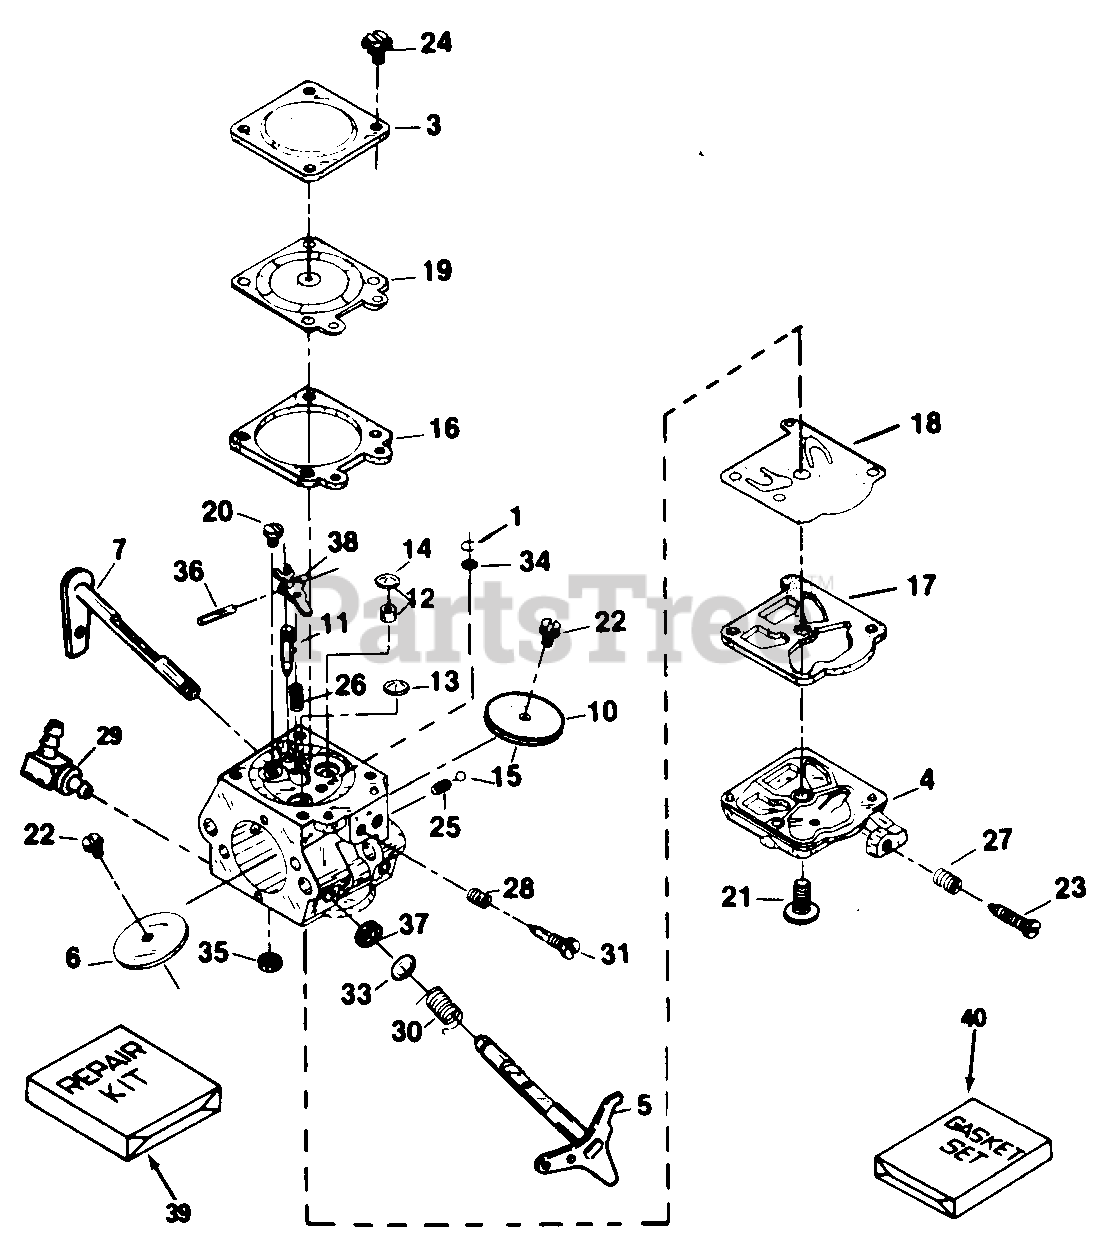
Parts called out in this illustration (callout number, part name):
1	Ring, Screen Retaining
3	Cover, Metering Diaphragm
4	Cover, Pump
5	Shaft Ass'y., Throttle
6	Shutter, Throttle
7	Shaft Ass'y., Choke
10	Shutter, Choke
11	Valve, Inlet Needle
12	Nozzle Ass'y., Check Valve
13	Plug, Welch (5/16")
14	Plug, Welch (1/4")
15	Ball, Choke Friction
16	Gasket, Diaphragm
17	Gasket, Pump
18	Diaphragm, Pump
19	Diaphragm Ass'y.
20	Screw, Metering Lever Pin
21	Screw, Pump Cover
22	Screw, Shutter
23	Screw, Idle Speed
24	Screw, Metering Cover
25	Spring, Choke Friction
26	Spring, Metering Lever
27	Spring, Idle Speed Screw
28	Spring, Idle Needle
29	Fitting, Fuel Line
30	Spring, Torsion
31	Needle, Idle
33	Washer, Throttle Shaft
34	Screen, Check Valve
35	Screen, Fuel Inlet
36	Pin, Metering
37	Seal, Throttle Shaft
38	Lever, Metering
39	Repair Kit
40	Gasket Kit
